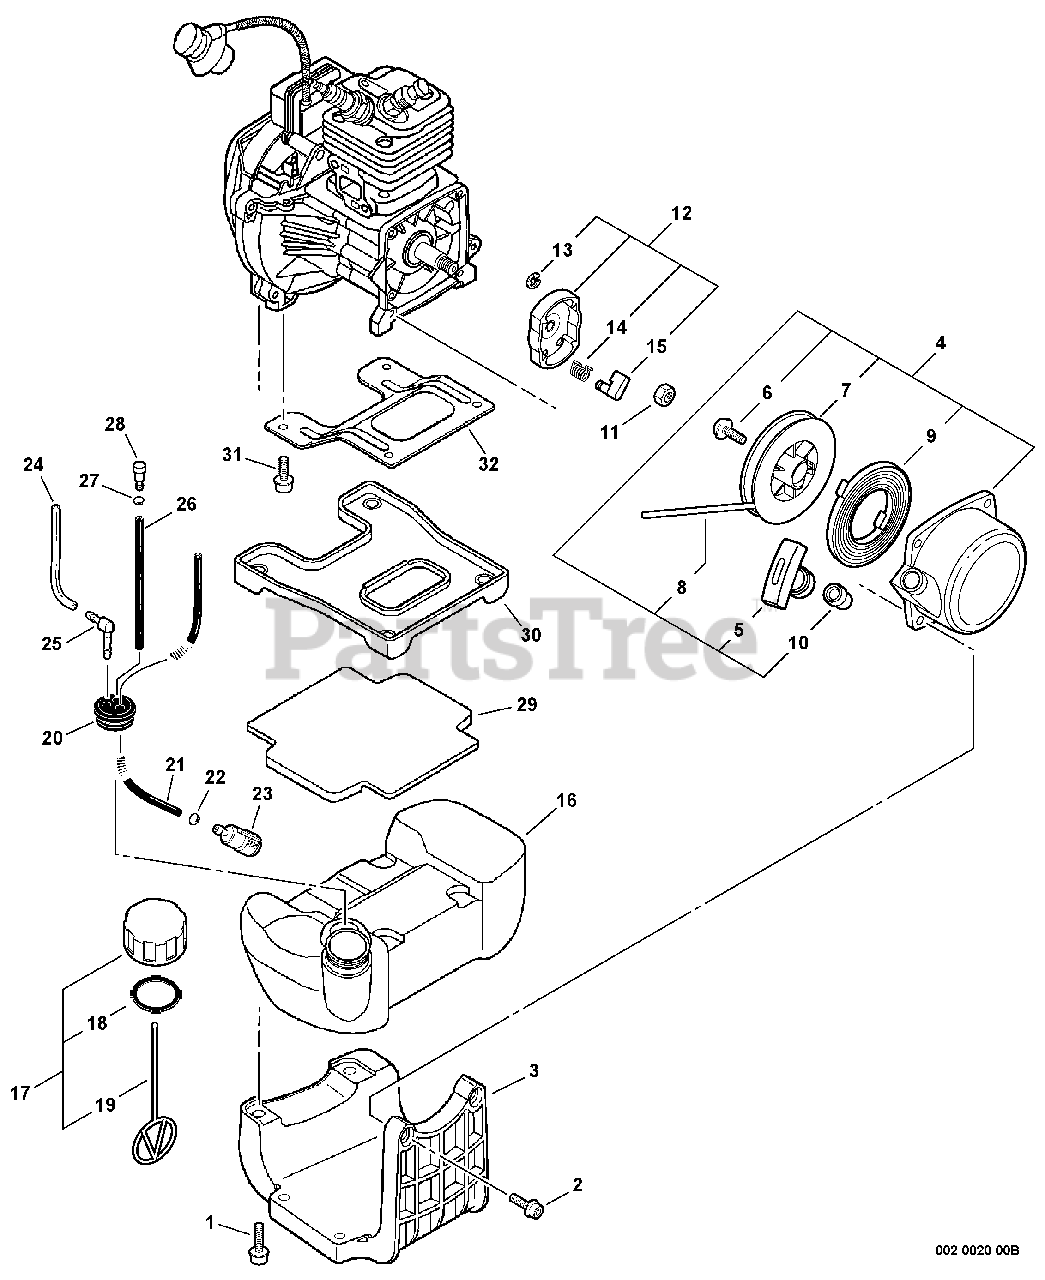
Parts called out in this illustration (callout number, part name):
1	SCREW - 5X20
2	SCREW - 5X25
3	BRACKET, FUEL TANK
4	STARTER ASSY
5	GRIP, STARTER
7	REEL, ROPE
8	ROPE, STARTER - 3.5X1000
9	SPRING, REWIND
10	GUIDE, ROPE
12	STARTER PAWL ASSY
13	RING, RETAINING - 4
14	SPRING, RETURN
15	PAWL, STARTER
16	TANK, FUEL
17	CAP ASSY - ORANGE
18	GASKET, CAP
19	CONNECTOR, CAP
20	GROMMET
21	PIPE - 3X6X180 -- BLACK
22	CLIP - 6.5
23	FILTER, FUEL
24	PIPE - 3X6X60 -- CLEAR
25	CONNECTOR, PIPE
26	PIPE - 3X6X120 -- BLACK
27	CLIP - 6.5
28	VENT, FUEL TANK
29	CUSHION, TANK - LOWER
30	CUSHION, TANK - UPPER
31	SCREW - 5X12
32	BRACKET, FUEL TANK
